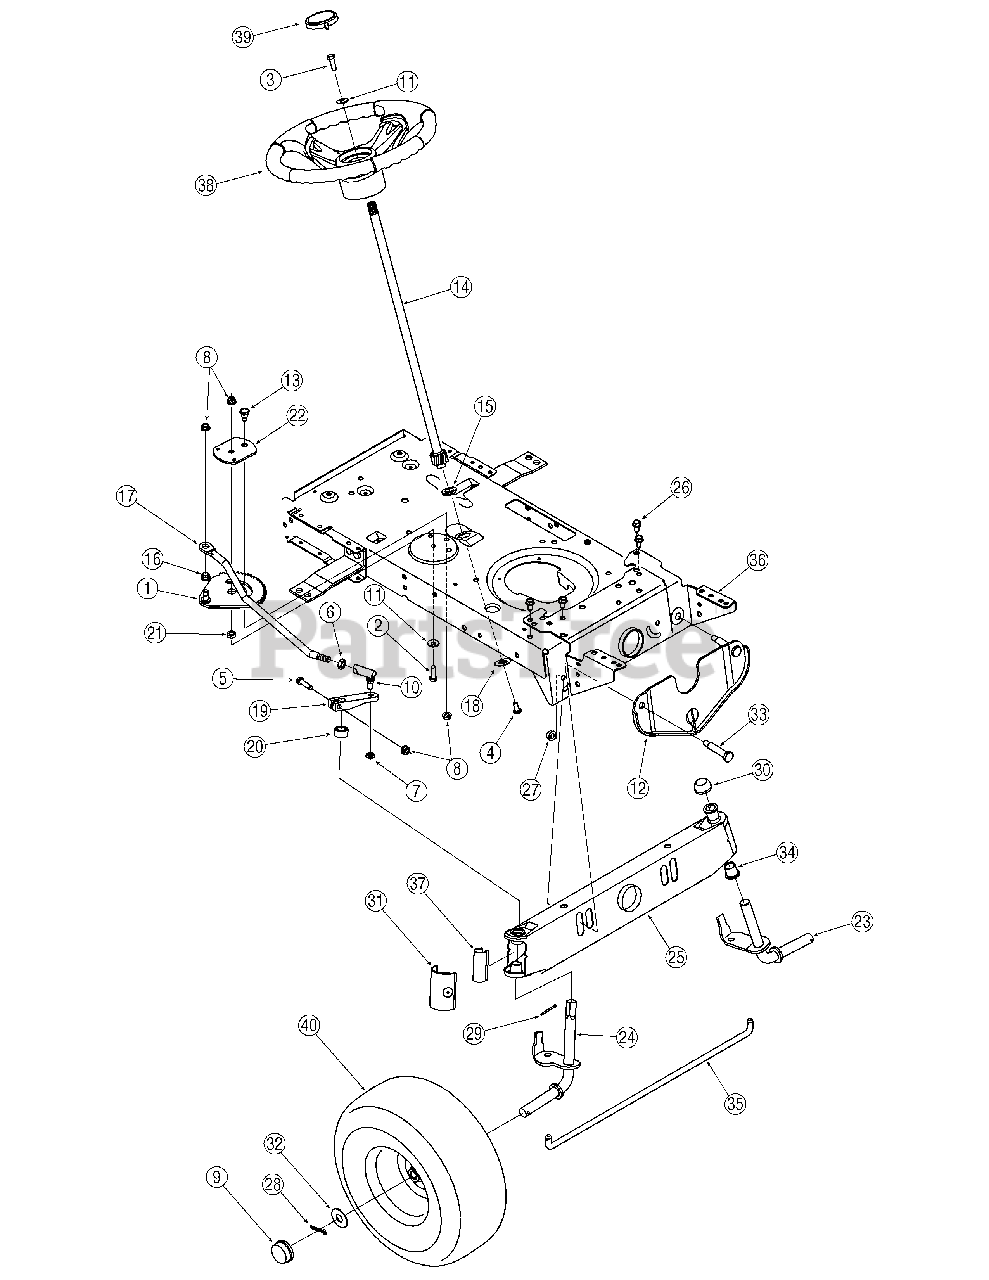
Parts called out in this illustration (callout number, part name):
1	Gear Assembly, Steering
2	Screw, 5/16-18, 1.00, Gr5
3	Screw, 5/16-18, 1.00, Gr5, Lock
4	Screw, Mach, 5/16-18, 0.750
5	Screw, 5/16-18, 1.75, Gr5
6	Nut, Jam, 7/16-20, Gr2
7	Nut, Jam Lock, 3/8-24, Gr2
8	Nut, Flange Lock, 5/16-18, Grf
9	Hub Cap
10	Ball Joint, 7/16-20, Lock
11	Washer, Bell, .340 x .872 x .060
13	Scr., Shlder, .435 x .3485, 5/16-18
14	Steering Shaft, 5/8 Spline x 21.86
15	Bearing, Flange, Hex 5/8
16	Plastic Bushing .380 ID
17	Drag Link, Steering
18	Cap, 1.25 x .16
20	Spacer, .710 ID x .125
21	Spacer, .322 ID x .625
22	Stabilizer Plate, Gear Segment
26	Screw, 5/16-12, 0.750
27	Nut, Flange Lock, 3/8-16, GrF
28	Pin, Cotter, 5/32, 1.25
29	Pin, Cotter, 1/8 x 1.25
30	Push Cap, 3/4
31	End Cap, Pivot Bar
31	End Cap, Pivot Bar (w/Fitting)
32	Washer, Flat, .78 x 1.59 x .060
33	Scr., Shlder, .500 x 2.380, 3/8-16
34	Bearing, Flange, .760 x .941
37	Axle End Cap, Standard
38	Steering Wheel, Standard
38	Steering Wheel, Soft Grip
39	Cap, Steering Wheel (no logo)
39	Cap, Steering Wheel (sprig)
39	Cap, Steering Wheel (tine logo)
